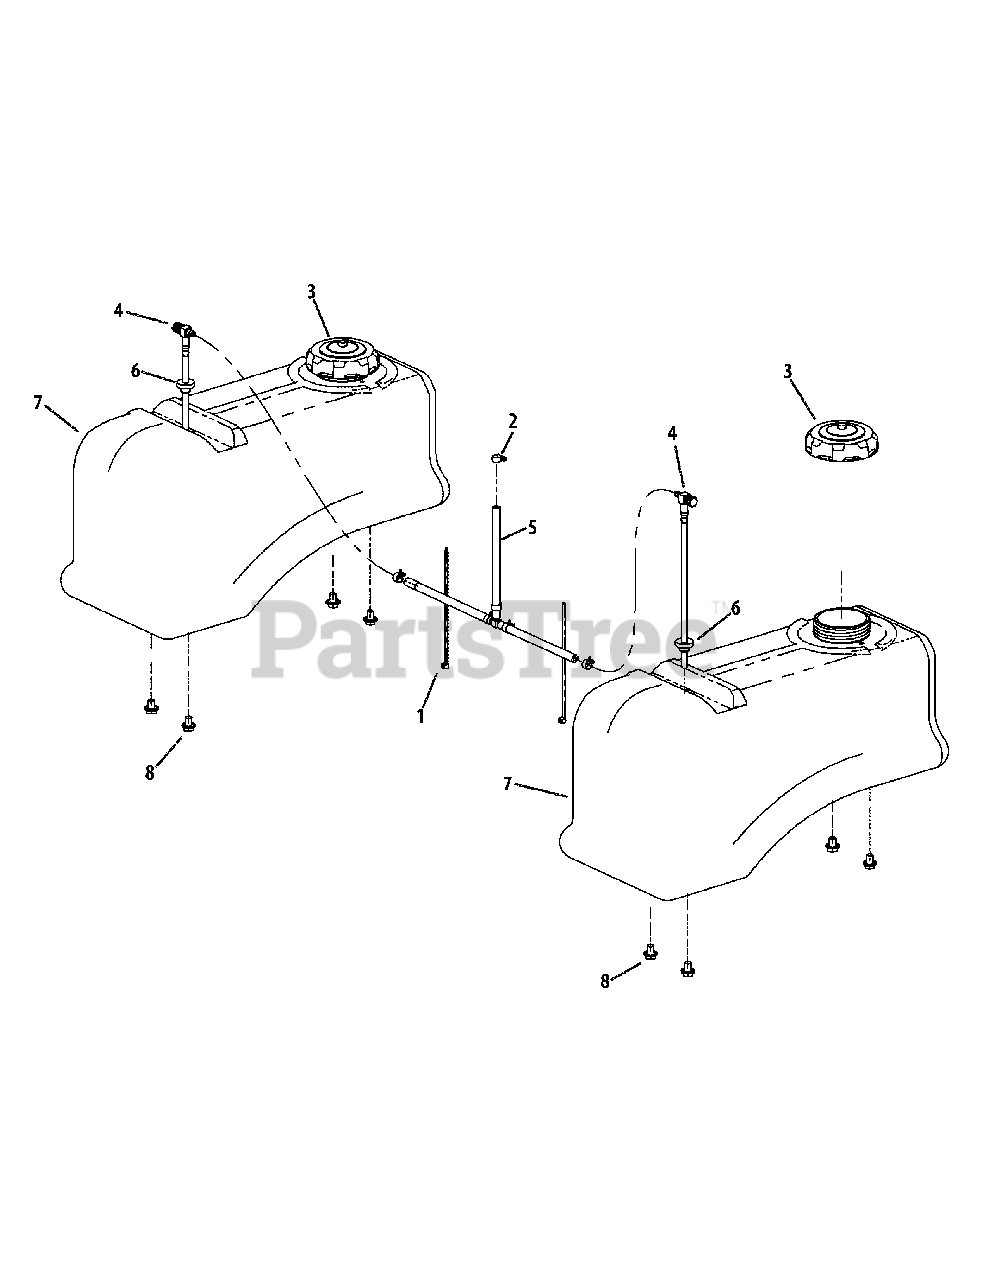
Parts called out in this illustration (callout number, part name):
1	Cable Tie
2	Hose Clamp
4	Fuel Fitting
5	Fuel Hose Assembly
6	Fuel Tank Grommet
7	Fuel Tank
8	Hex Screw, 3/8-16 x .50
